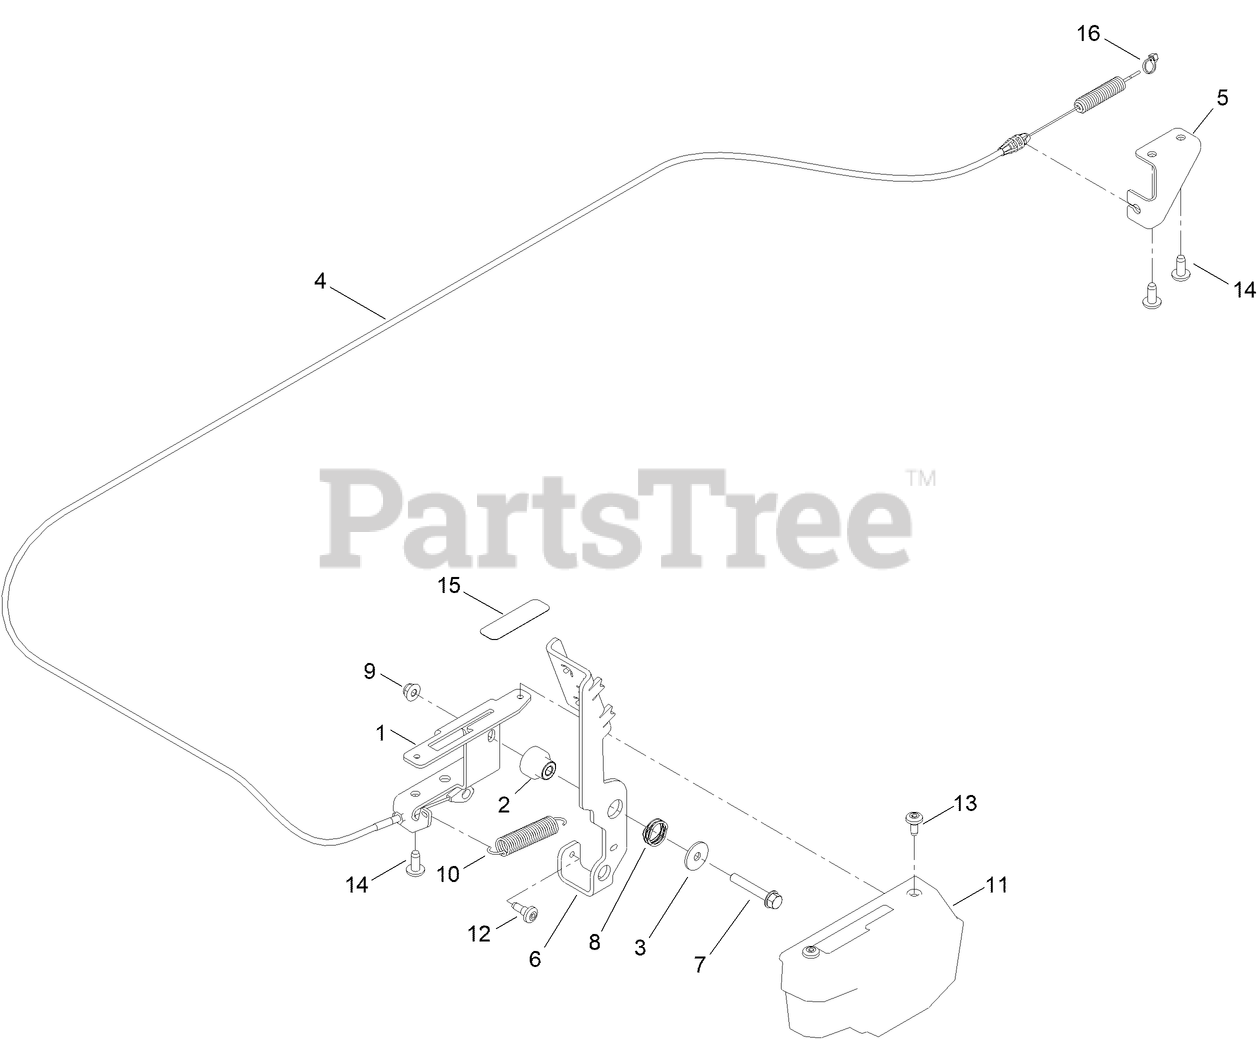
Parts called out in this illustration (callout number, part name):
1	BRACKET-PEDAL, BRAKE
2	BUSHING-FLANGE
3	WASHER-PIVOT
4	CABLE-BRAKE
5	BRACKET-CABLE, BRAKE
6	PEDAL-BRAKE
7	SCREW-HHF
8	WASHER-WAVE
9	NUT-HF
10	SPRING-PEDAL, RETURN
11	COVER-BRAKE, PARKING
12	SCREW-SHOULDER
13	SCREW-SHOULDER
15	DECAL-BRAKE, PARKING
16	TIE-CABLE
